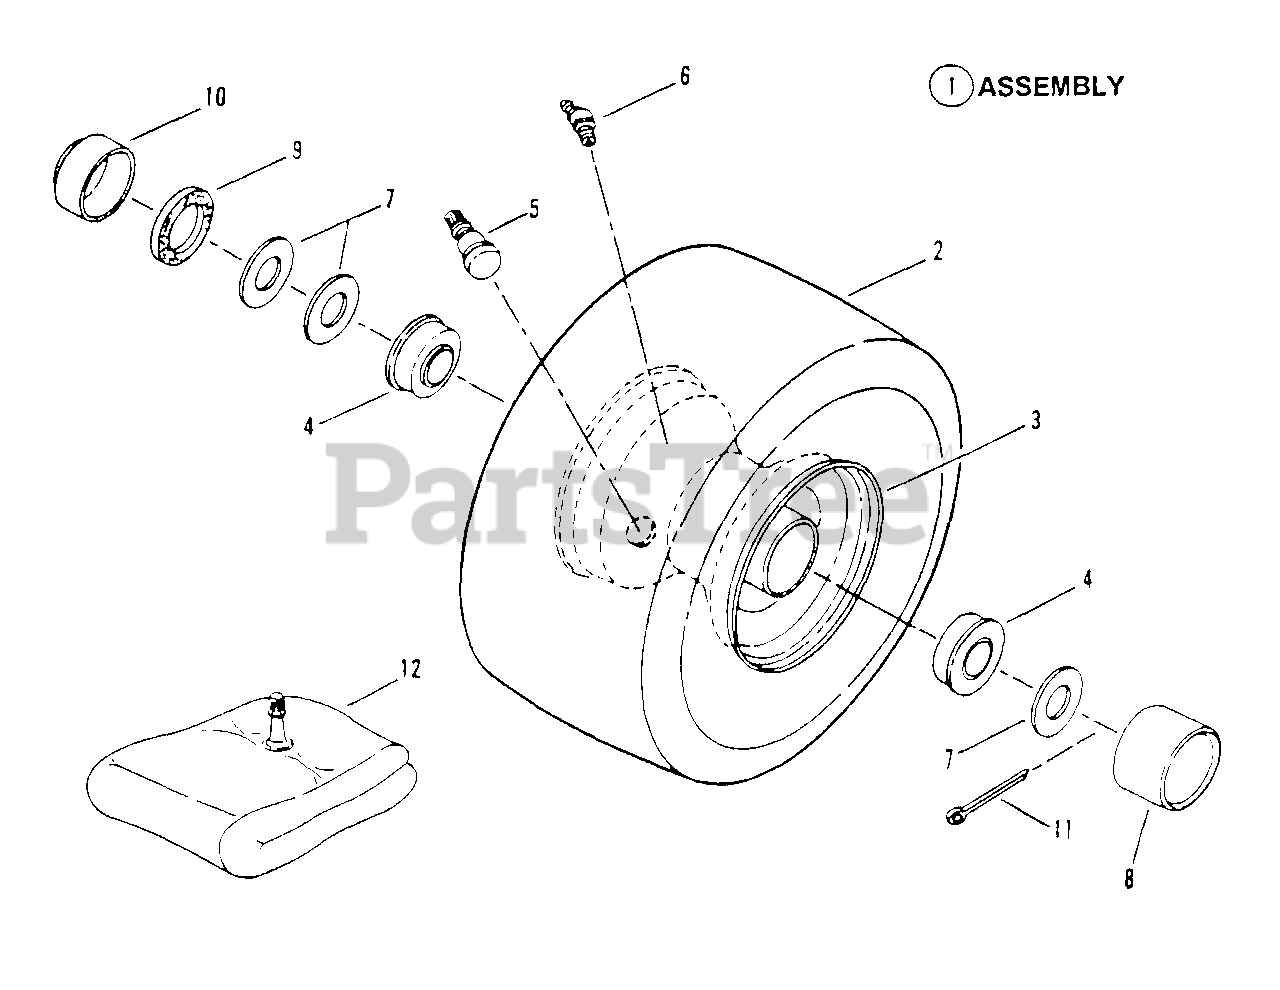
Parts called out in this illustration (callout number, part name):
1	ASSEMBLY, Tire & Rim
2	TIRE, 4.10/3.50 x 4
3	RIM
4	BEARING, Ball
5	VALVE, Air (Snap-in)
6	FITTING, Lube
7	WASHER
8	CAP, Hub
9	SEAL, Felt
10	CAP, Dust
11	PIN, 5/32 x 1" Cotter Hair
12	TUBE, Inner
